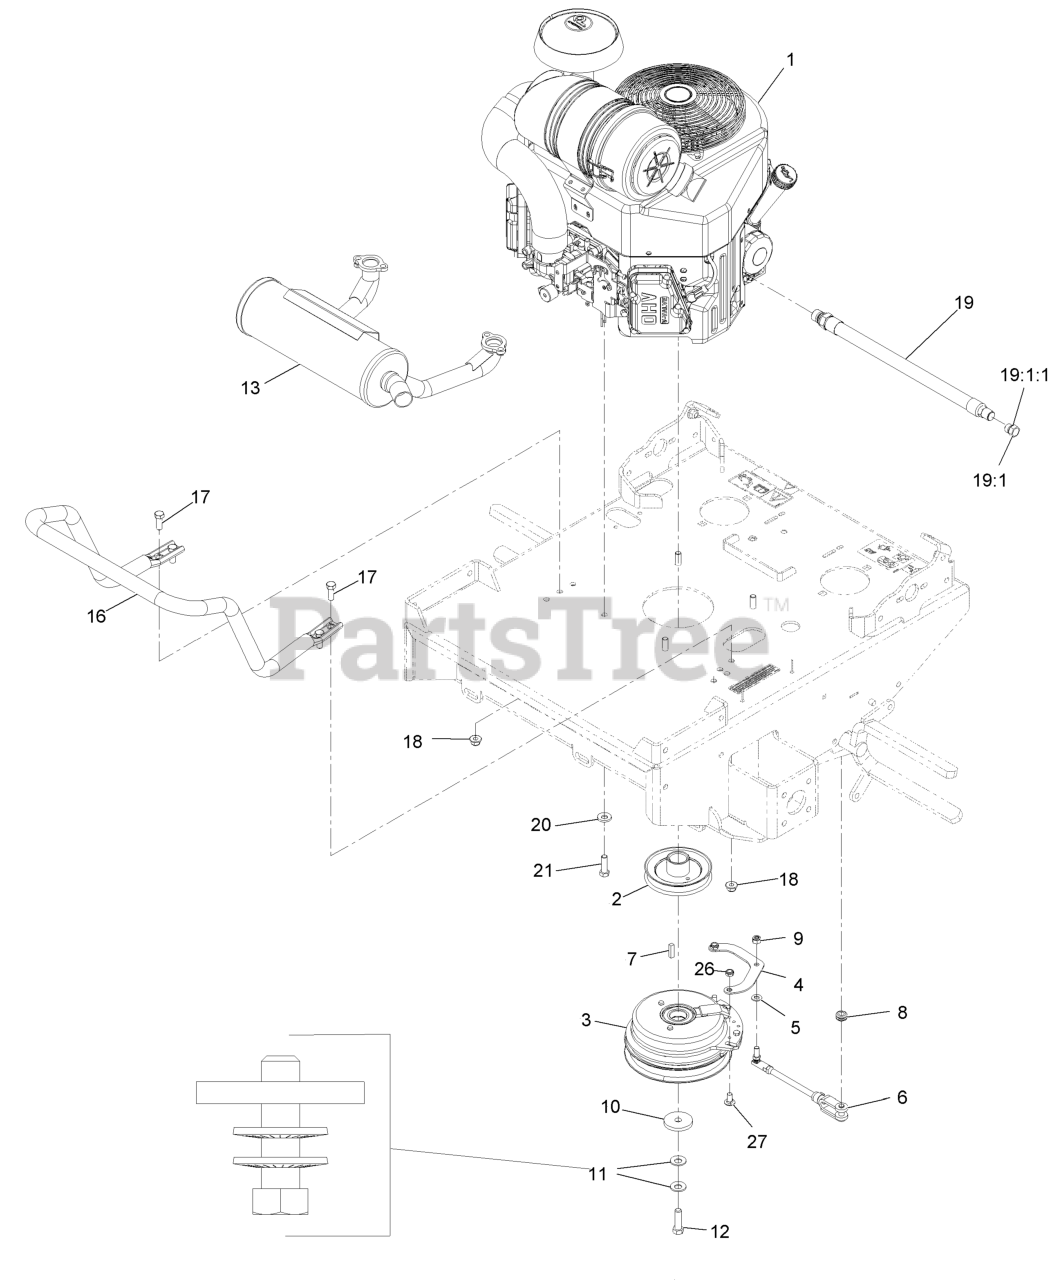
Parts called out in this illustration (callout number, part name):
2	SHEAVE W/ HUB
3	CLUTCH, 200 FT/LBS, 1.13
4	STRAP, CLUTCH
5	WASHER-PLAIN
6	ASM, CLUTCH ANCHOR
7	KEY
8	GROMMET
9	NUT-LOCK
10	WASHER-CLUTCH
11	WASHER-SPRING
12	BOLT-HEX, TAP
13	MUFFLER,HORIZONTAL
16	GUARD-MUFFLER
17	SCREW-HH
18	NUT-HF, NI
19	ASM, ENGINE OIL DRAIN HOS
19:1	PLUG-HH
19:1:1	O-RING
20	WASHER-BELLEVILLE
21	SCREW-HH
26	NUT-LOCK, NI
27	SCREW-CARR
